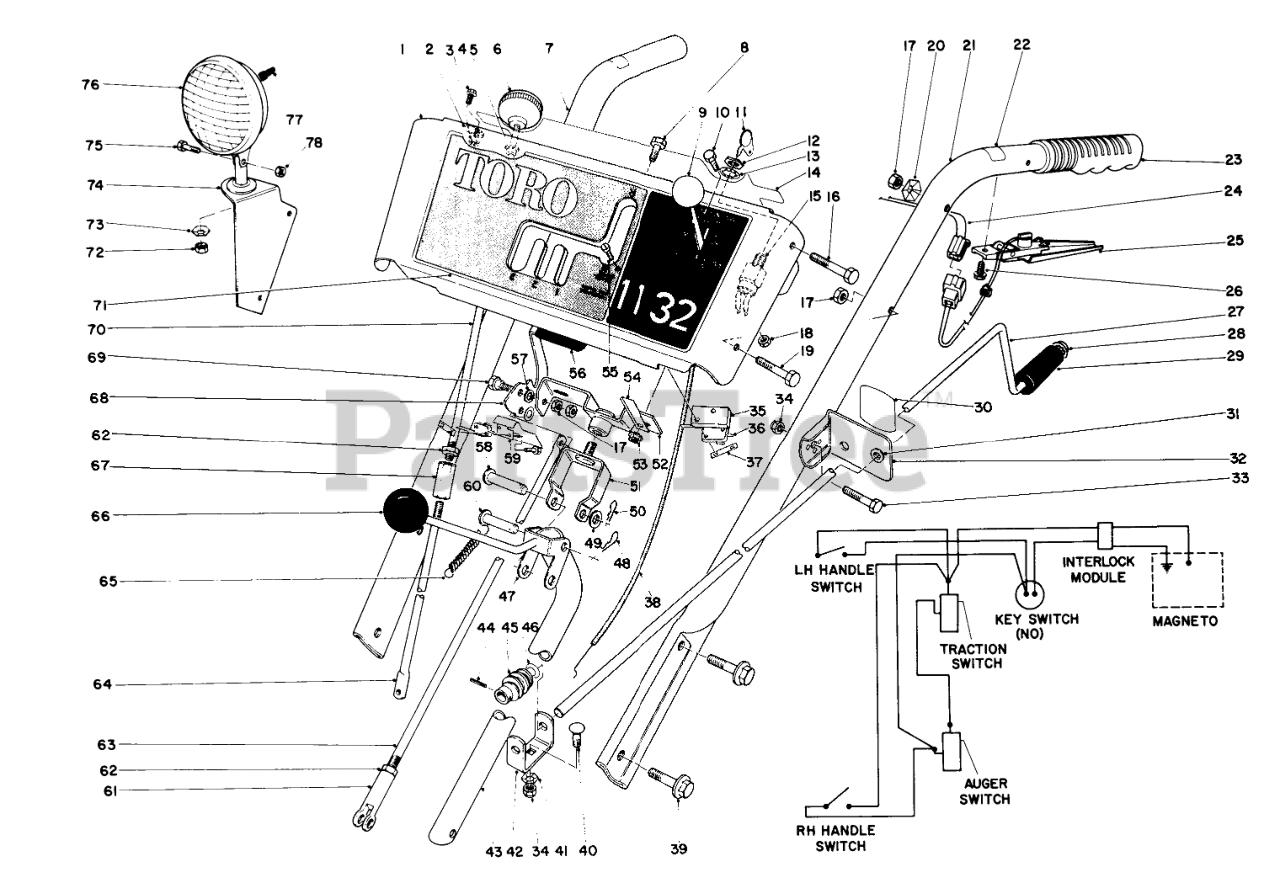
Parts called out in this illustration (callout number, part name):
1	Escutcheon Plate (Incl. Ref. #13 & 71) (Model 38160)
2	CLAMP-NYLON
3	NUT-KEPS
5	NYLINER #6LI-FF TYPE 7
6	KNOB-LEVER
7	Handle Right
8	SCREW-HH
9	CONTROL KNOB
10	HEX HEAD SEMS 10-24X1/2
11	Key
13	WASHER-TOOTH, INTERNAL
14	BACK ESCUTCH DECAL
15	Key Switch
16	SCREW-HH
18	Nut
19	SCREW-HH
20	Washer
21	HANDLE LEFT
22	INTERLOCK DECAL
23	Grip Handle
24	WIRE HARNESS INTERLOC
25	INTERLOCK HDLE SWITCH
26	SCREW
27	Chute Control Rod
28	RETAINER-PUSH ON
29	GRIP-CONTROL, CHUTE
30	CHUTE DECAL
31	Bushing
32	Bracket-Chute Control Mounting (Incl.Ref. #30 & 31)
33	SCREW-HH
34	NUT-LOCK, NI
35	SWITCH MTG PAD
36	SWITCH-MICRO
37	NUT-SPEED
38	Throttle Contrl
39	SCREW-HHF
40	BOLT-CARR
41	WASHER-LOCK
42	WORM BRACKET
43	Rod Traction Shift
44	PIN-SPRING
45	GEAR-WORM, CHUTE
46	WASHER-SPRING
47	SHIFT ROD WA
48	PIN-COTTER
49	WASHER-FLAT
50	PIN-HAIR
51	PIVOT BRKT WA
52	SWIVEL BLOCK WA
53	NUT-LOCK, HHF
54	Retainer Wire
55	SCREW-SPH
56	AUGER CLUTCH HND GRIP
57	WASHER-PLAIN
58	PIN-CLEVIS
59	SWITCH BRKT
60	PIN-CLEVIS
61	Clevis
62	NUT-HJ
63	DRAG LINK
64	Grass Basket
65	CONT ROD SPRING 0
67	WHL ROD COUPLING
68	Auger Clutch Handle
69	SCREW-SHOULDER
70	UP WHEEL CLUTCH ROD
71	ESCUTCHEON DECAL
72	NUT-HEX
73	LOCKWASHER-PYRAMID
74	Lamp Mount
75	SCREW-HH
76	HEADLAMP ASM
77	BOOT-SWITCH
